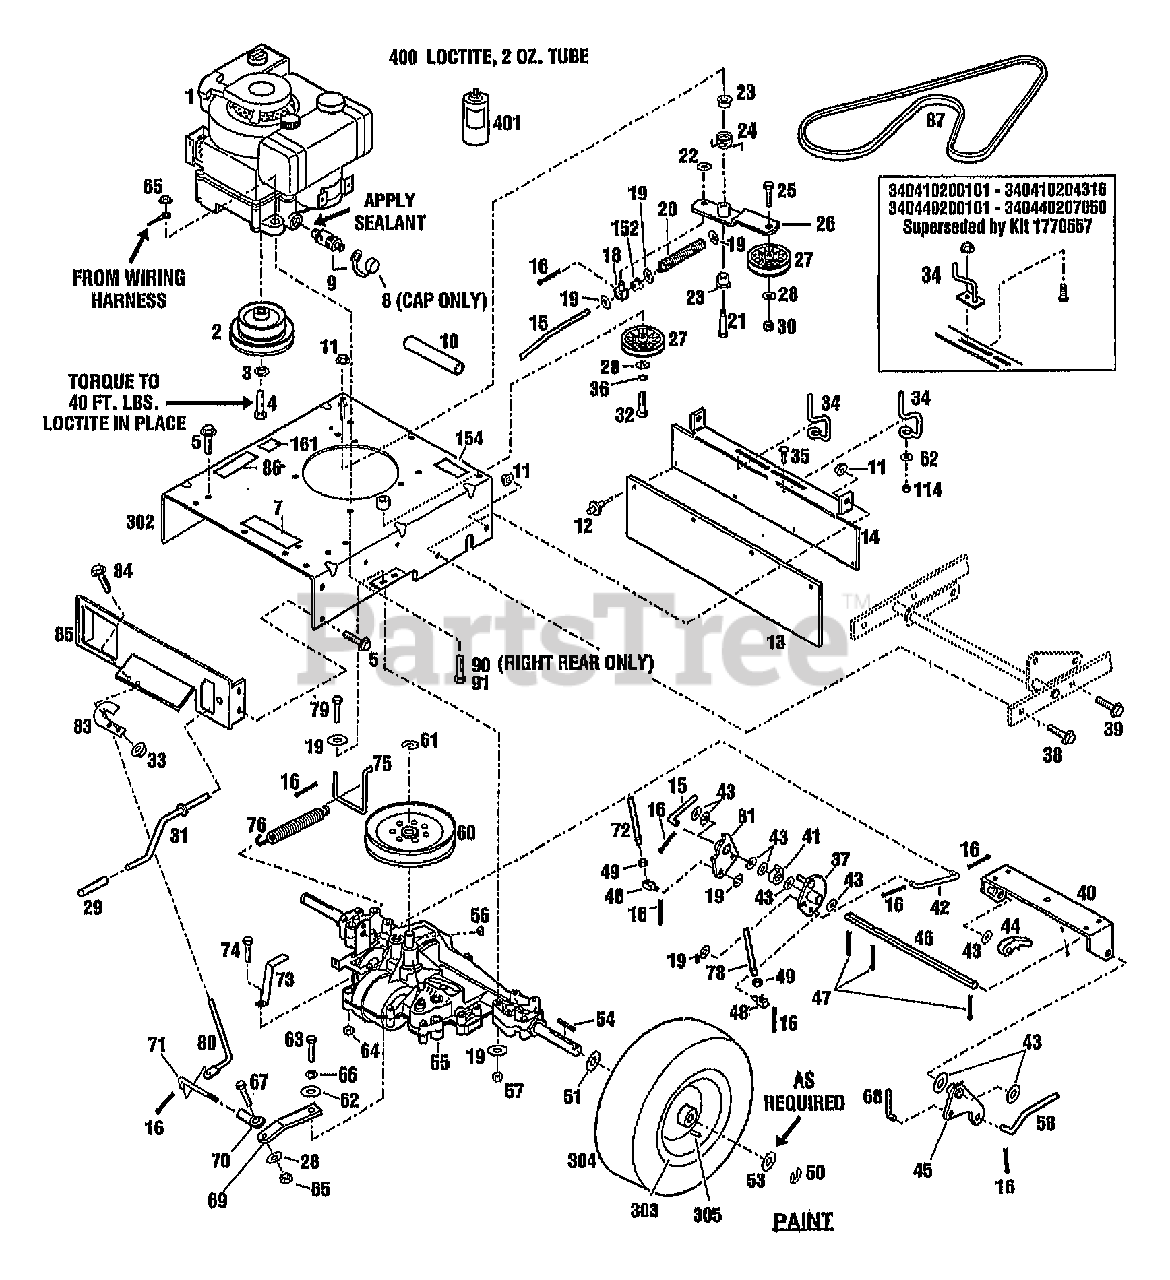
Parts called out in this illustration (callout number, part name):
1	ENGINE, 8.5HP ELEC. START MODEL 196707- 0141 (34041)
1	ENGINE, 8.5HP RECOIL START MODEL 196702- 0142 (34044)
2	ENGINE SHEAVE-HW&WC (SUPERCEDES 1764991)
3	WASHER-LK .438 ZP
4	SCR-HH 7/16-20X1.25 G5ZP
5	SCR-HFLK 5/16-18X.62 G5ZP
7	DECAL-WARNING
8	CAP-OIL DRAIN
9	ASSM-OIL VALVE (INCL. 8)
10	HOSE-OIL DRAIN
11	NUT-HFLK 3/8-16 ZP
12	RIVET-POP 3/16 X 5/8
13	FLAP-DEFLECTOR
14	BRACKET-FLAP MTG
15	ROD-LOWER TRANS
16	PIN-COTTER .093X.625
18	BLOCK-PIVOT
19	WASHER-FLAT 5/16 SAE
20	SPRING-COMPRESSION
21	SCR-SHLDR 3/8-16
22	WASHER-.632X.39X.0329
23	BUSHING-.5X.5 NYLON FLNG
24	SPRING-TORSION
25	SCR-CARR 3/8-16X1.75 G5 ZP
26	ASSM-IDLER ARM ZP
28	WASHER-FLAT 3/8 SAE
29	GRIP-PLASTIC
30	NUT-LOCK 3/8-16
31	ASSM-CRANK LIFT
32	SCR-HH 3/8-16X1.75 G5 ZP
33	NUT-HF/LK 1/4-20 ZP
34	KIT-BELT GUIDE
34	ASSM-BELT GUIDE
35	SCR-CARR 1/4-20X.75 G2 ZP
36	WASHER-LK .375 @ DEPL
37	ASSM-BRAKE ARM PIVOT
38	SCR-HFLK 3/8-16X1.25 ZP
39	SCR-HFLK 3/8-16X1.00 ZP
40	ASSM-PIVOT BRACKET
41	CAM-INTERLOCK
42	ROD-LOWER BRAKE
43	WASHER-FLAT 1.0X.516X.031
44	LATCH-INTERLOCK
45	ASSM-BLADE PIVOT ARM
46	SHAFT-PIVOT
47	PIN-COTTER .125 X .75 ZP
48	BLOCK-SWIVEL ZP
49	NUT-HEX JAM 5/16-18
50	RING-RET."E".577 ID
51	WASHER-1.5X.755X.062
53	WASHER-1.25X.765X.049
54	KEY-.188 SQ X 2.5
55	PEERLESS TRANSMISSION ASSEMBLY, MODEL 915- 021 (SEE GRIDS D-9/10 FOR BREAKDOWN)
56	KEY-WOODRUFF .188X.75
57	NUT-TOP/LK 5/16-18 ZP
58	ROD-LOWER BLADE
60	SHEAVE-TRANS DRIVE
61	RING-RETAIN .625 ID
62	WASHER-FLAT 1/4 SAE
63	SCR-HH 1/4-28X.75 G5 ZP
64	NUT-HFLK 5/16-18 ZP
65	NUT-H/LK 3/8-16
66	WASHER-LK .25 ZP
67	SCR-HH 3/8-16X1.25
68	ROD-UPPER BLADE
69	ARM-TRANSMISSION ZP
70	JOINT-BALL
71	ROD-SHIFT LINK
72	ROD-UPPER TRANS MOWER
73	BRKT-BELT SUPPORT
74	SCR-HH 5/16-18X2.00
75	ROD-SPRING ATTACHMENT
76	SPRING-EXTENSION
78	ROD-UPPER BRAKE
79	SCR-HH 5/16-18X2.75 G5 ZP
80	ASSM-SHIFT LEVER
81	ASSM-CLUTCH ARM PIVOT
83	BRKT-SHIFT ROD MTG
84	SCR-HFLK 1/4-20X.50 ZP
85	PLATE-BACK
87	BELT-TRANS DRIVE
90	SCR-THRD FRM 3/8-16X1.50
91	SCR-HH 3/8-16X1.0 THDFM
114	NUT-HT LK 1/4-20
154	DECAL-AMERICAN LEGEND-SM
161	DECAL-STEP
302	ASSM-FRAME (INCL. 7 & 86)
304	TIRE
305	STEM-VALVE
401	PAINT-RED SPRAYCAN POWDER
